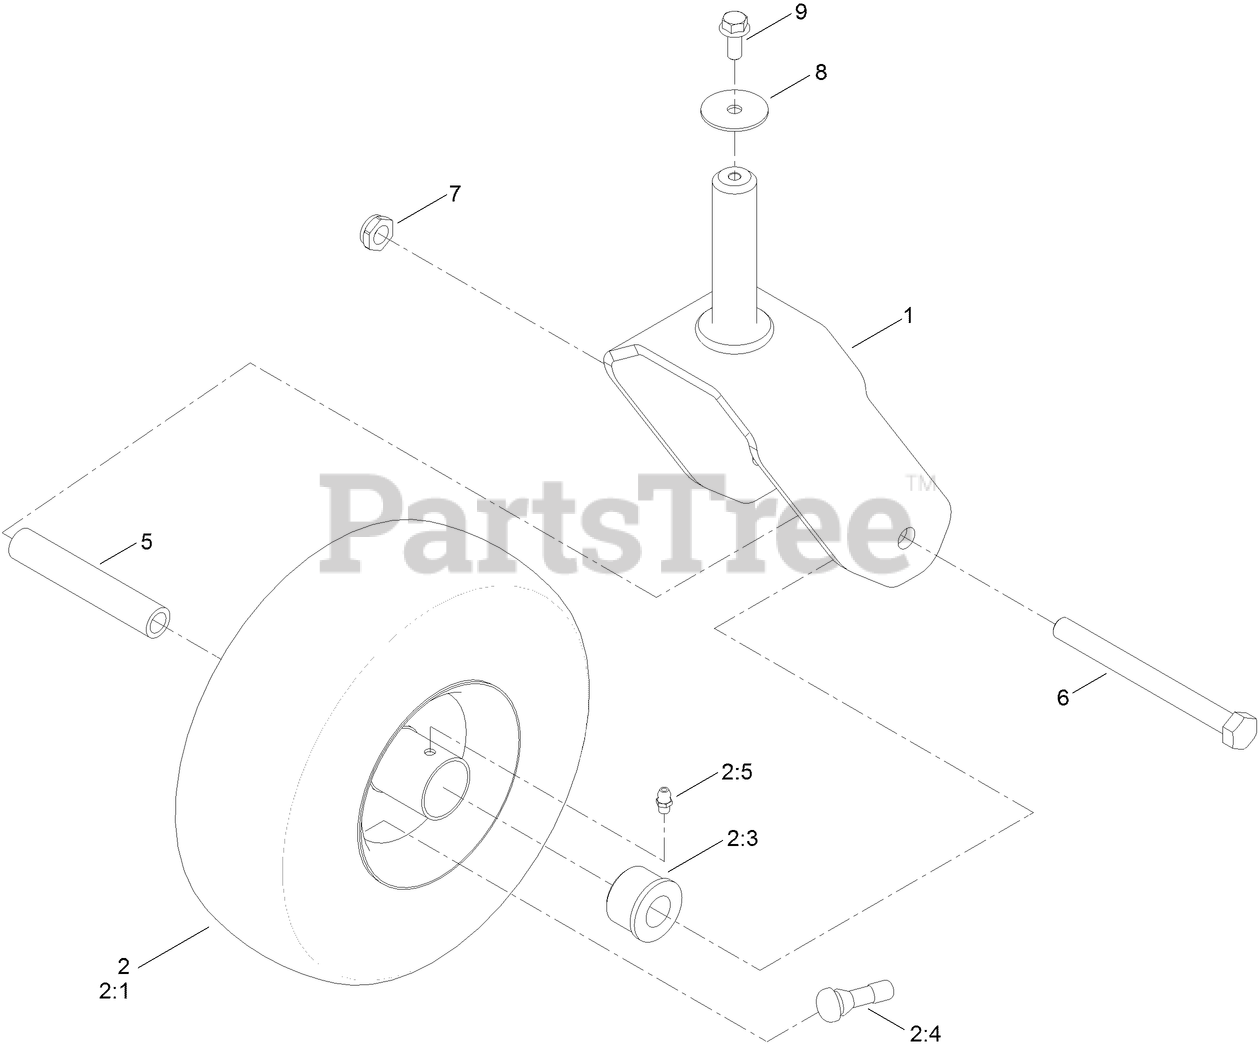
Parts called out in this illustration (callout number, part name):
1	FORK ASM
2	TIRE ASM
2:1	TIRE
2:3	BUSHING-FLANGE
2:5	FITTING-GREASE
2:99	TUBE-INNER
5	BUSHING-SPANNER
6	SCREW-HH
7	NUT-LOCK, NI
8	WASHER-FLAT
9	SCREW-HHF
